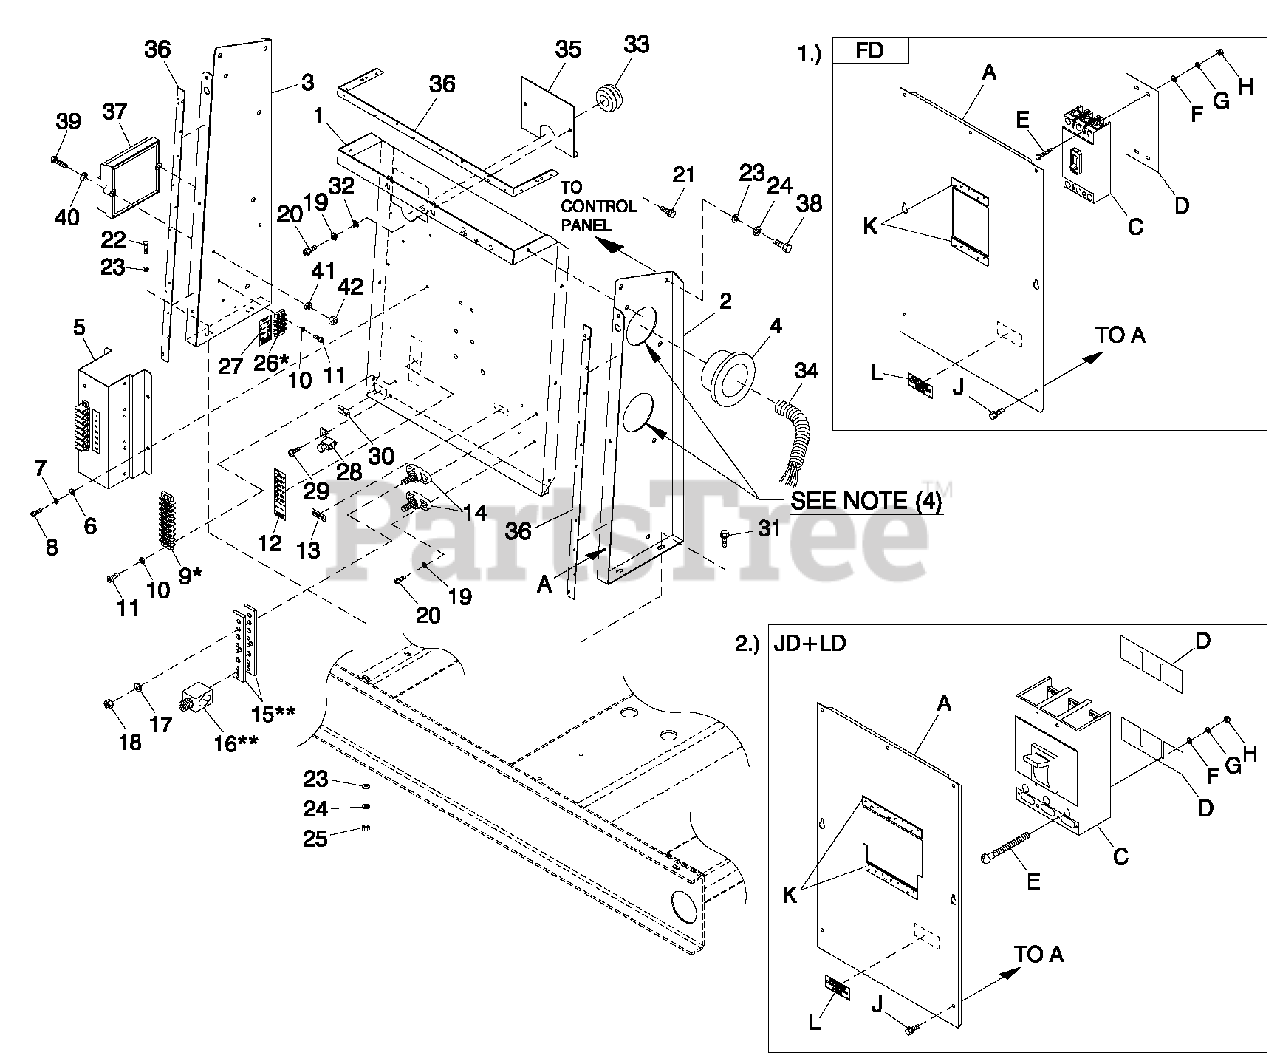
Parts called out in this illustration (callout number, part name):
1	PANEL CB CONN BOX
1	UL CIRCUIT BREAKER (FD)
2	STAND RH CONTROL
2	UL CIRCUIT BREAKER (JD+LD)
3	STAND LH CONTROL C5 GRBX
4	BUSHING SNAP SB-2.5-31
5	ASSY PCB INTERFACE 1PH 240V
6	WASHER FLAT M4
7	WASHER LOC K#8-M4
8	SCREW PHTTM4-0.7X 10 ZYC
9	BLOC K TERM 20A 8 X 6 X 1100V
10	WASHER LOC K#6
11	SCREW PHTT # 6 -3 2X1 /2 ZYC
12	DECAL CPL CUST CONN H CTRL
13	DECAL NEUTRAL
14	JUNCTION BLOC K 3/8-16
15	BUS BAR NEUTRAL BLOC K 390
16	LUG SLDLSS 600/250-1/0 X 1/4-28
17	WASHER LOC K3/8
18	NUT HEX 3/8-16 STEEL
19	WASHERLOCK M5
20	SCREW PHTT M5-0.8X 16 ZYC
21	SCREW THF M6-1 X 16 N WA Z/JS
22	SCREW HHC M 6-1.0X20G 8.8
23	WASHER FLAT 1/4-M6 ZINC
24	WASHER LOCK M6-1/4
25	NUT HEX M6X 1.0 G8YEL CHR
26	BLOCK TERM 20A 6 X 3 X 1100V
27	DECAL CUST CONN 120V UTILITY
28	LUG SLDLSS #6-14X 13/64 CU
29	SCREW HHTT # 10-32X3/8 CZ
30	DECAL GROUND LUG
31	SCREW HHTT M6-1.0X 16ZYC
32	WASHER FLAT M5
33	GROMMET 1.25 X .25 X .75
34	CONDUIT FLEX 2.0" ID
35	PLATE WIRE SNGLGALV
36	TAPE ELEC 1/2 FOAM (AS REQ'D)
37	ASSY PCB 4.6L IGNITION MODULE
38	SCREW HHC M6-1.0X 16 G8.8
39	SCREW PPHM # 1 0 /32X 2
40	WASHER FLAT #10 ZINC
41	WASHER LOCK #10
42	NUT HEX #10-32 STEEL
A	COVER FD FRMCB
C	CB0150A3P 600V S FD6 LL
D	INSULATOR CB FD FRAME 30MIL
E	SCREW SHC 1/4-20 X 4 G8.8 NZ
F	WASHER FLAT 1/4-M6 ZINC
G	WASHER LOCK M6-1/4
H	NUT HEX 1/4-20 STEEL
J	SCREW THF M6-1 X 16 N WA Z/JS
K	TAPE ELEC 1/2 FOAM (AS REQ'D)
L	DECAL CUSTOMER CONNECT INSIDE
A	COVER C IRBRKRJD/LD
C	CB0300A3P 600V SJD6 LL
D	INSULATOR CIRCUIT BR. JD/LD
E	SCREW RHM 1/4 -20X 3
